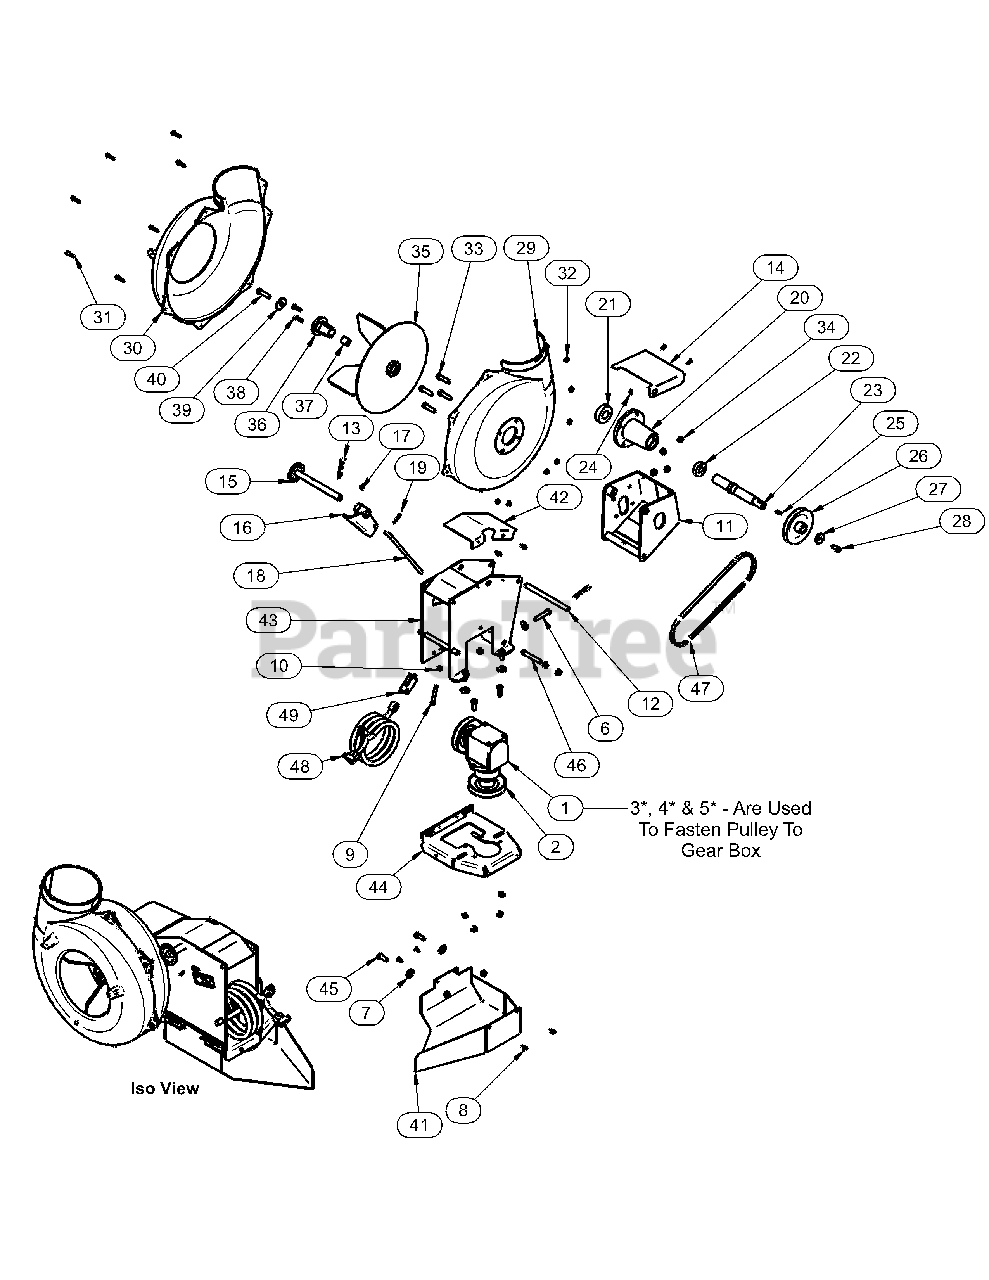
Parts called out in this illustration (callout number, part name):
1	GEAR BOX-RIGHT ANG
2	GEAR BOX PULLEY AS
3	SNAP RING-RETAININ
4	WOODRUFF KEY #9
5	SCREW-SET 5/16-18
6	BOLT-HEX 3/8-16 X
7	WASHER-FLAT 3/8
8	SCREW-HEX HEAD 1/4
9	BOLT-CONE 5/16-18
10	NUT-FLANGE 5/16-18
11	PTO BLOWER MOUNT B
12	BLOWER PIVOT ROD
13	HAIR PIN CLIP
14	BLOWER BELT GUARD
15	HANDLE MOUNT ASSEM
16	CAM BRACKET ASSY
17	SCREW-SET 3/8-16
18	BELT TENSION ROD
19	CLIP-HAIR PIN
20	PTO SHAFT HOUSING
21	BEARING-LARGE
22	SMALL BEARING
23	PTO SHAFT
24	GREASE FITTING
25	KEYWAY-3/16 X 3/4
26	BLOWER PULLEY
27	WASHER-1.187 OD
28	HEX BOLT-3/8-16 X
29	PTO BLOWER HOUSING
30	PTO BLOWER HOUSING
31	HEX BOLT-1/4-20 X
32	NUT-FLANGE 1/4-20
33	BOLT-HEX 3/8-16 X
34	FLANGE-3/8-16
35	IMPELLER-4 BLADED
36	TAPERED BUSHING 1"
37	BUSHING/SPACER
38	BOLT-HEX 1/4-20 X
39	WASHER-7/16 X 1-3/
40	SCREW-HEX HEAD 3/8
41	GEAR BOX-PULLEY GU
42	PTO ARM GUARD
43	PTO ARM ASSEMBLY
44	BASE PLATE
45	BOLT-HEX 3/8-16 X
46	BOLT-HEX 3/8-16 X
47	BELT-V 4L320
48	HARNESS-SAFETY INT
49	SWITCH-PLUNGER
